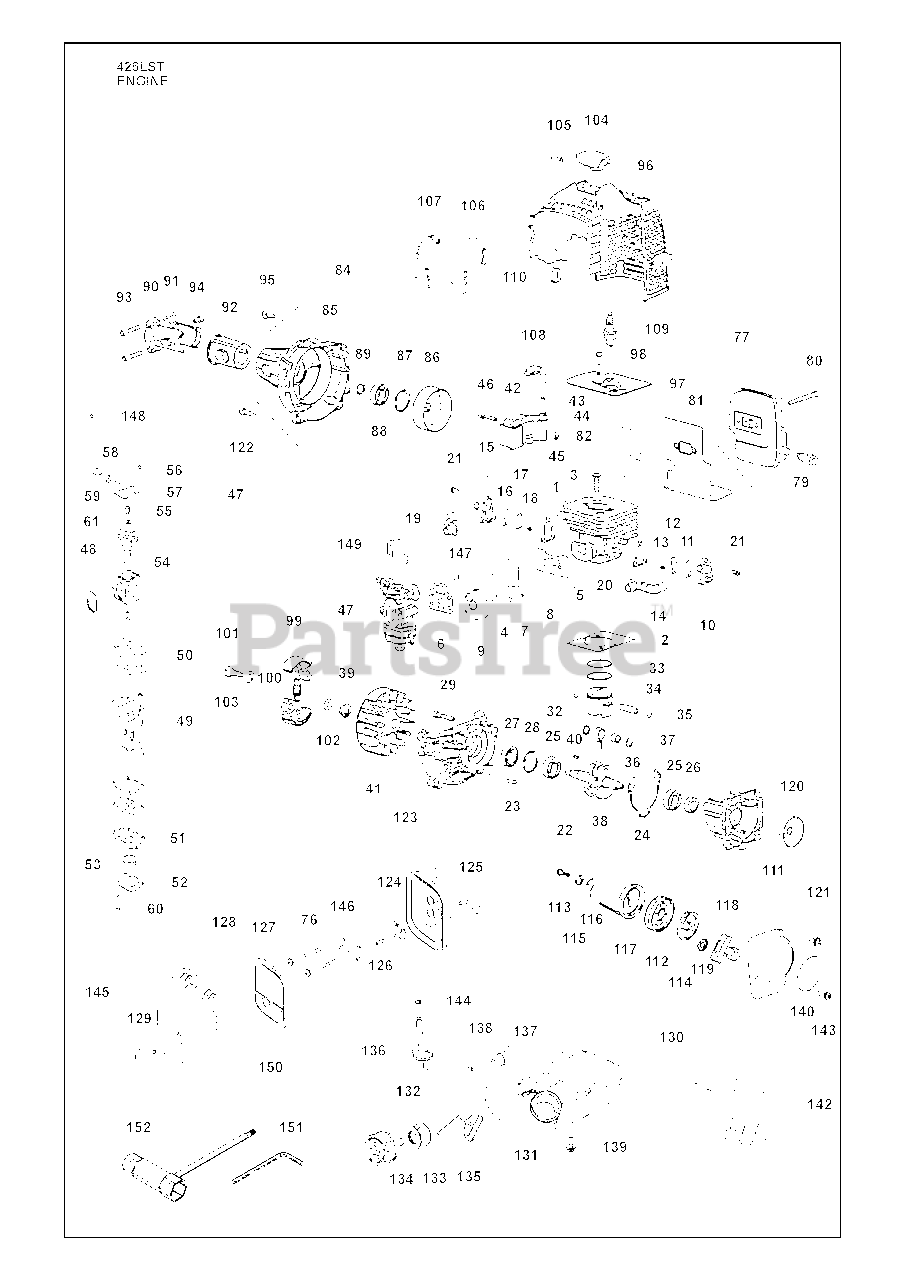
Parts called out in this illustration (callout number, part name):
2	GASKET, BASE
5	GASKET, INSULATOR
6	GASKET, CARB (RPLS T155113131)
10	AIR CHECKER (S) ASSY
14	PIPE AIR (S)
15	AIR CHECKER (F) ASSY
19	PIPE AIR (F)
20	GASKET, VALVE
22	CRANKCASE-C
24	GASKET.CASE
25	BEARING
34	PIN (RPLS T151341310)
38	CRANKSHAFT COMP(RPLS481042000)
39	NUT
44	CAP
47	CARBURETOR WYA-138
48	REBUILD KIT
49	CARBURETOR BODY
50	GASKET KIT
58	NUT
59	SCREW CABLE ADJUST
82	PLATE, MUFFLER
84	Cover, Complete
90	BRACKET(A)-24
91	BRACKET(B)-24
96	COVER ENGINE
98	BOLT 08
107	CORD.EARTH
108	TUBE (RPLS 263072210)
109	SPARK PLUG NGK CMR7H
114	SPRING, SPIRAL
119	PLATE.STOPPER
121	BOLT M5X14
124	PLATE, CHOKE
127	ELEMENT
128	COVER ASSY
130	TANKA
136	PIPE-C
137	FILTER
140	LABEL RECOIL
147	BOLT
150	TOOL SET (RPLS 848-8UD-0120)
152	SOCKET
